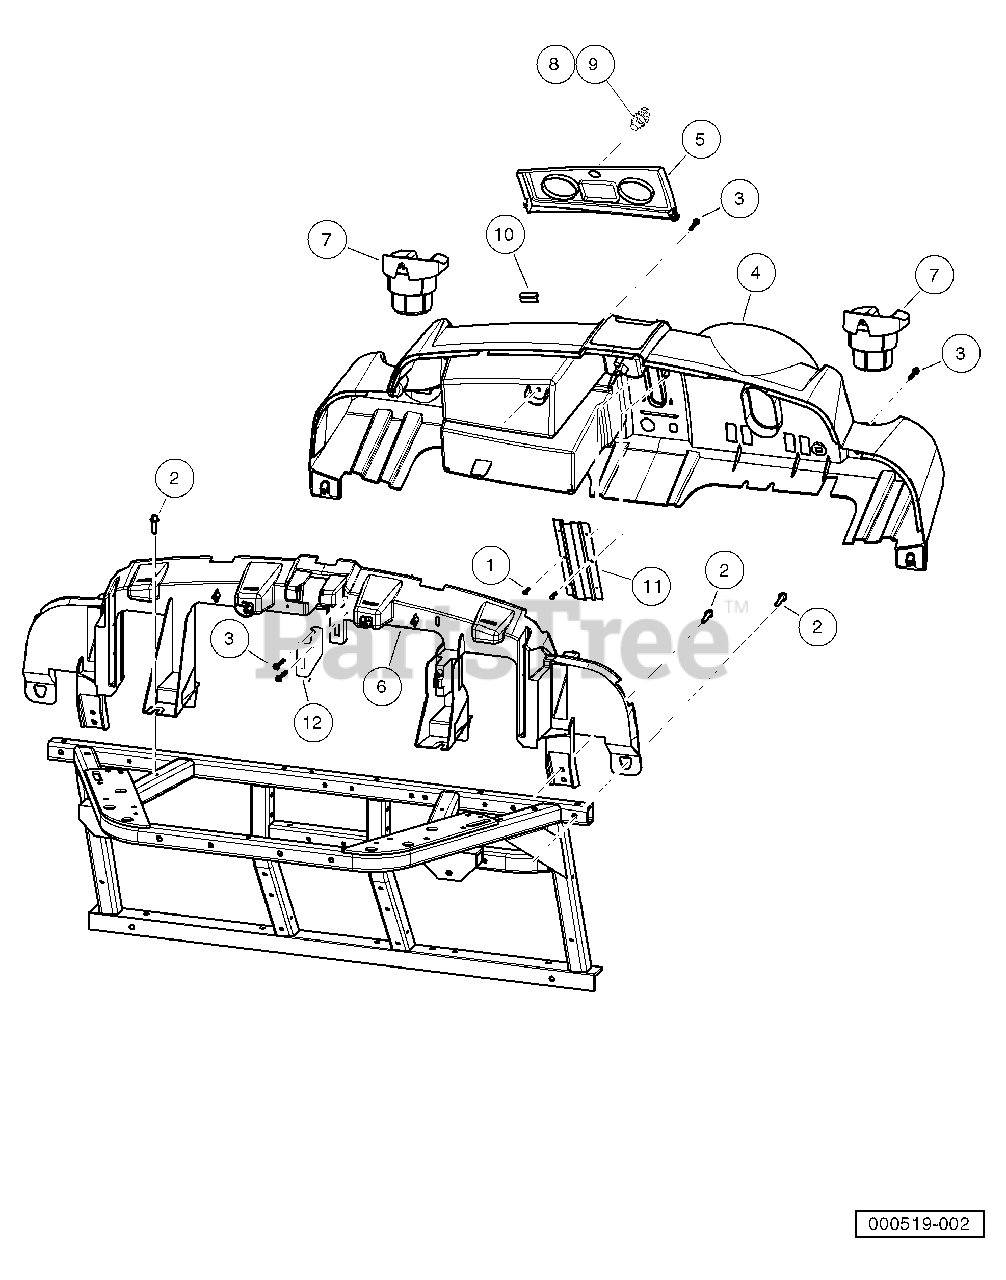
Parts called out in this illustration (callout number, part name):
1	Screw, #8 X 0.500, Hex-Head Hi-Lo
2	Screw, M8X1.25X30, Hex
3	Screw,m6,torx,interlock,thread
4	Dash, Design A
5	Cover, Storage, Dash, Awd, Huv
6	Support, Structural
7	Cup Holder, Utility
8	Latch, Push Close
9	Latch, Push Close W/ Key
10	Keeper, Latch, Push Close
11	Asm, Brush, Fnr
12	Bracket, Hood Support
